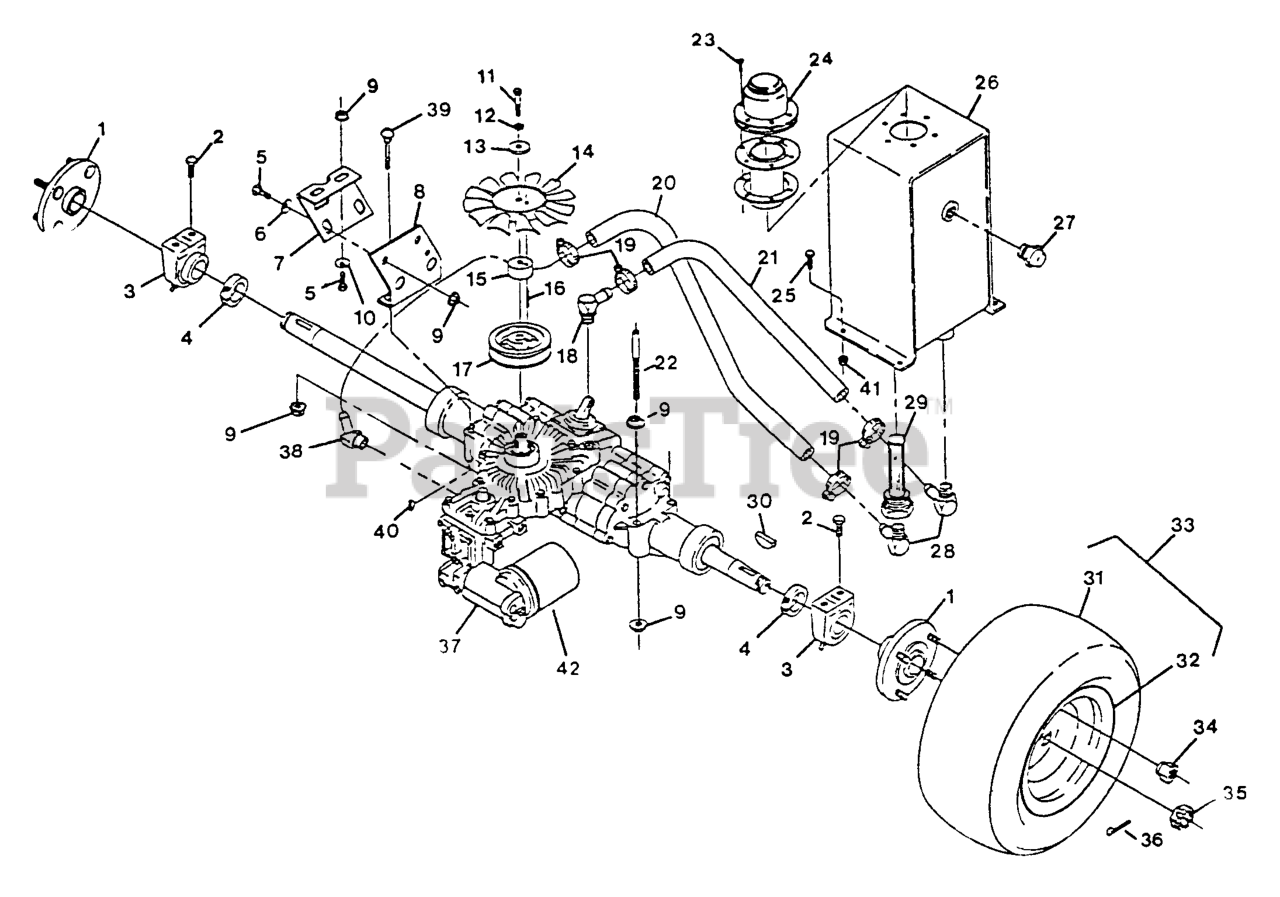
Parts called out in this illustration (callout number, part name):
2	SCREW-HHF
3	BEARING,PILLOW BLOCK
5	SCREW-HH
6	WASHER-BELLEVILLE
8	STABILIZER,AXLE LOWER
9	NUT-HHF, WHIZ
10	WASHER-FLAT
11	SCREW-HH
12	WASHER-LOCK
13	WASHER-RETAINER, PULLEY
14	FAN,7"OD/10BLADE
15	SPACER,FAN
19	CLAMP-HOSE
20	HOSE,HYDRAULIC 16.5
21	HOSE,HYDRAULIC 8.0
22	PIN,GUIDE
24	BREATHER,FILLR & CAP
25	SCREW-HH
27	OIL EYE,HYDRAULIC TANK
29	STRAINER,SUCTION
30	KEY-WOODRUFF
33	WHEEL AND TIRE ASM
34	NUT-LUG
35	NUT-HEX, SLOTTED
36	PIN-COTTER
38	ELBOW-45DEGOR/HSEBRB
39	BOLT,CARRSSN
40	KEY-WOODRUFF
